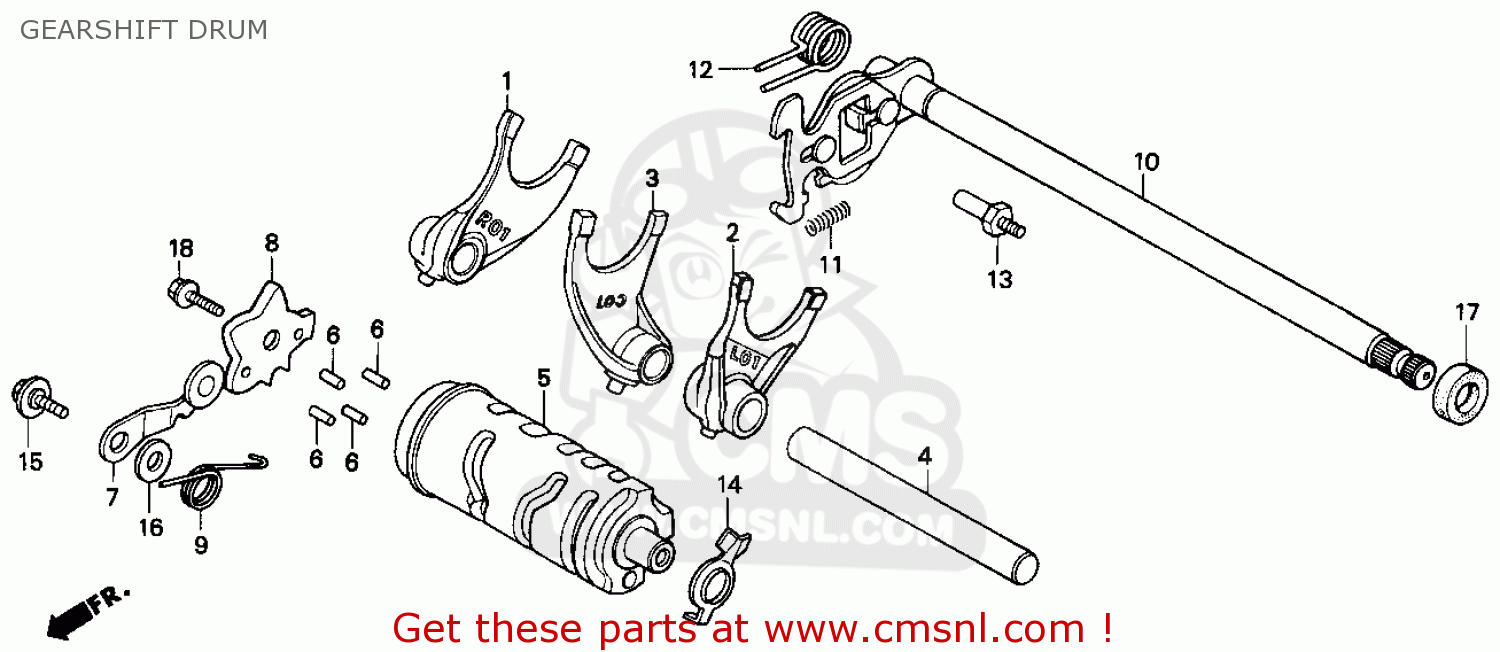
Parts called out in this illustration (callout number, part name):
1	FOR,R,GEARSHIFT
2	FORK,L,GEARSHIFT
3	FORK,CENTER G/SFT
4	SHAFT,GEAR SHIFT
5	DRUM,GEARSHIFT
6	PIN,GEARSHIFT
7	STPR,SHIFT DRUM
8	PL,DRUM STOPPER
9	SPRING,SHIFT DRUM
10	SPINDLE COMP.,GEA
11	SPRING,GEAR SHIFT
12	SPRING,GEAR SHIFT
13	PIN, SHIFT RETURN
14	ROTOR,NEUTRAL SW.
15	PIVOT,SHIFT DRUM
16	WASHER,DRUM
17	OIL SEAL
